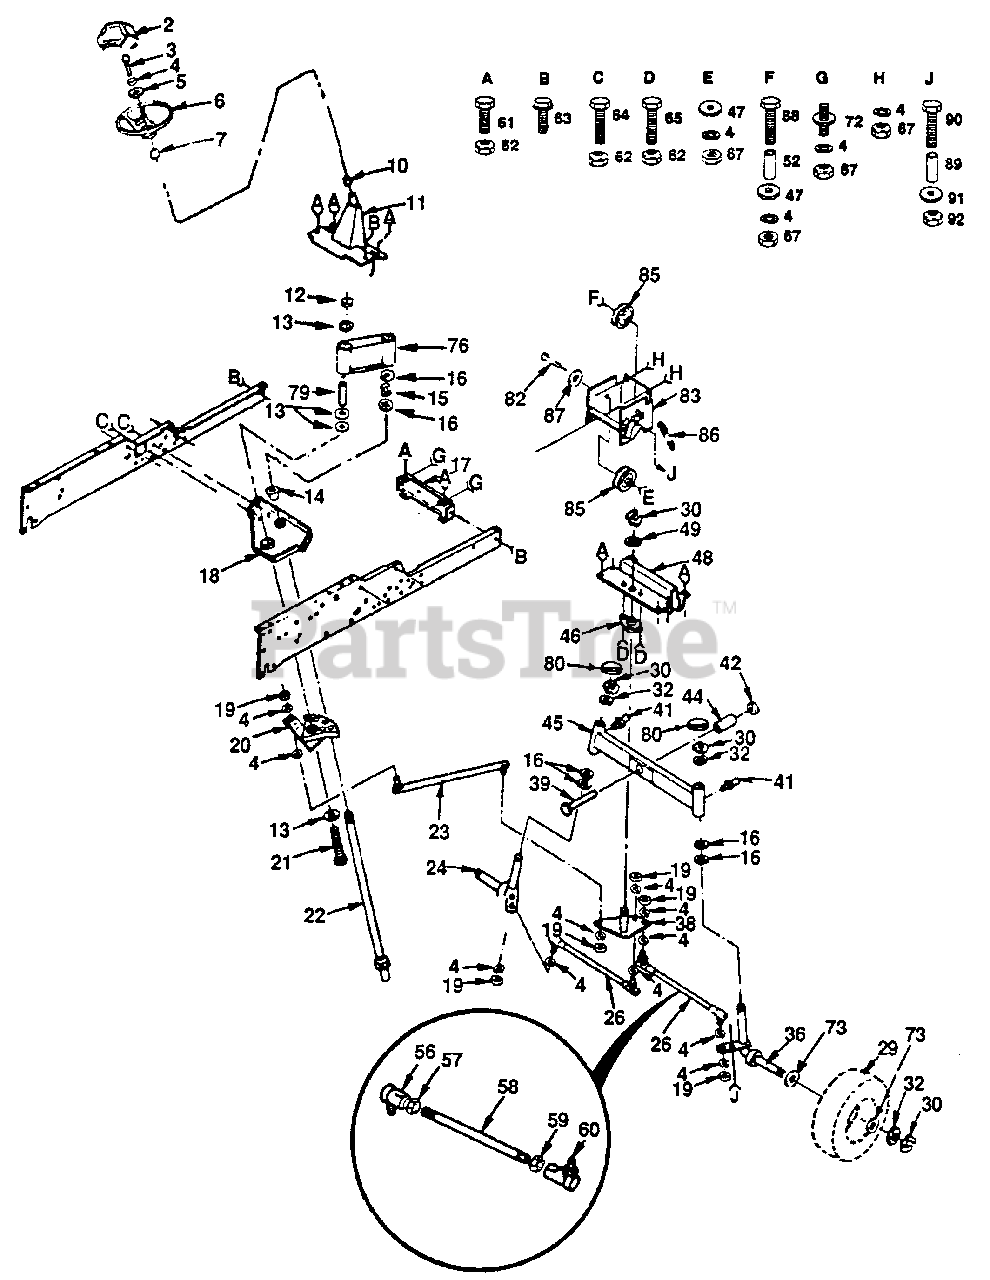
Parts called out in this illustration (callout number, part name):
2	Insert, Steering Wheel
3	Bolt, Hex 3/8-16 x 1 Grade 5
4	Washer, Lock 3/8
5	Washer 13/32 x 2-3/8 x 8 Gauge
6	Wheel, Steering
7	Adapter, Steering
11	Support Assembly, Steering
12	Locknut 1/2-13
13	Washer 17/32 x 1-5/8 x 10 Gauge
14	Bearing, Flanged
16	Bearing, Thrust
17	Bracket, Frame, Front
18	Bracket, Support, Steering
19	Nut, Hex 3/8-24
20	Sector Assembly
21	Bolt, Hex 1/2-13 x 5 Grade 5
22	Shaft, Steering
23	Link, Drag
24	Spindle, L.H.
26	Rod, Tie
32	Washer 17/32 x 1-1/2 x 10 Gauge
36	Spindle, R.H.
38	Bellcrank Assembly
39	Bolt, Hex 5/8-11 x 2-3/4 Grade 5
41	Fitting, Grease
42	Nut, Crownlock #10-24 UNC
44	Tube, Pivot, Axle
45	Axle Assembly, Front
46	Bushing, Bellcrank
47	Washer 13/32 x 7/8 x 13 Gauge
48	Bracket, Axle
49	Washer 29/32 x 1-1/4 x 16 Gauge
52	Spacer, Split
56	Joint, Tie Rod, L.H., Thread
57	Nut Hex, Jam 3/8-24 L.H.
59	Nut, Hex, Jam 3/8-24
60	Joint, Tie Rod, R.H., Thread
61	Bolt, Hex 3/8-16 x 3/4
62	Locknut 3/8-16
63	Screw, Hex Wsh. Thdrol. 3/8-16 x 3/4
64	Bolt, Hex 3/8-16 x 1 Grade 5
65	Bolt, Hex 3/8-16 x 1
67	Nut, Hex 3/8-16
72	Pin Mounting, Idler, Bracket
73	Washer 25/32 x 1-1/4 x 16 Gauge
76	Collar Weld Assembly
80	Dust Cap Cover
82	Bolt, Hex 3/8-16 x 2
83	Bracket, Idler
85	Pulley, Idler
87	Washer 13/32 x 2-3/8 x 8 Gauge
88	Bolt, Hex 3/8-16 x 2-1/4
89	Bushing, Handle
90	Bolt, Hex 5/16-18 x 1
91	Washer 11/32 x 7/8 x 16 Gauge
92	Locknut 5/16-18
